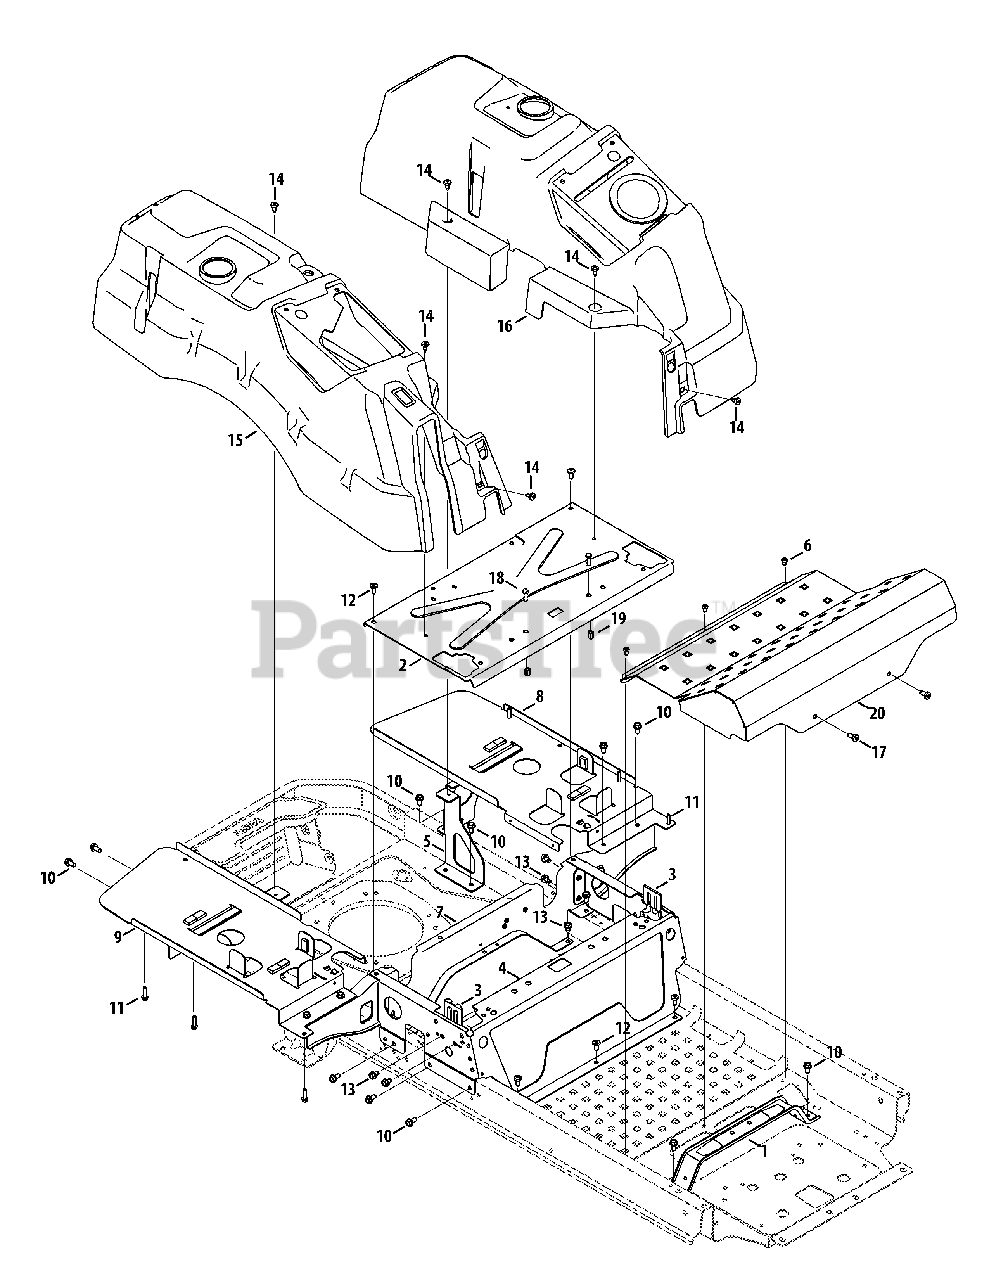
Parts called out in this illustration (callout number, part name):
1	Steering Support Bracket
2	Seatbox Plate
3	Lapbar Brace Bracket
4	Seat Frame
5	Rear Support Bracket, LH
5	Rear Support Bracket, RH
6	Screw, 1/4-20 x .50
7	Rear Seatbox Brace
8	Tank Support Plate, LH
9	Tank Support Plate, RH
10	Hex Washer Screw, 5/16-18 x .750
11	Hex Washer Screw, 5/16-14 x 1.00
12	Self Tapping Screw, 5/16-18 x .750
13	Hex Washer Screw, 5/16-18 x .50
14	Shoulder Screw, 1/4-20
15	RH Console
16	LH Console
17	Screw, 5/16-18 x .75
18	Hex Cap Screw, 5/16-18 x 1.00
19	Nut, 5/16-18
20	Floor Board, Fab
